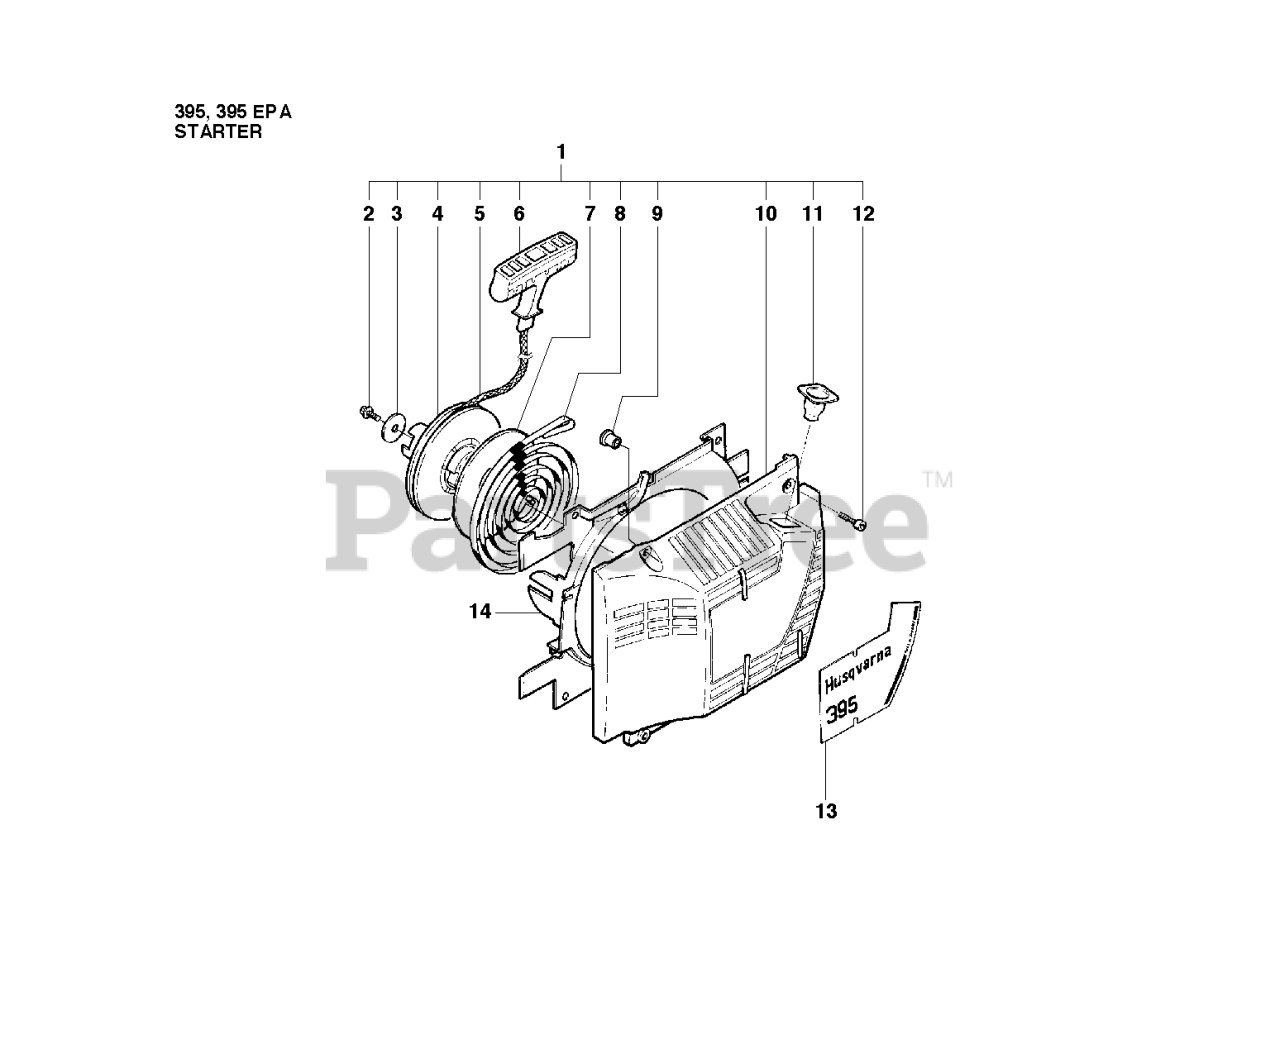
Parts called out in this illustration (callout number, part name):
1	STARTER HOUSING ASSY.
2	SCREW
5	STARTER ROPE
6	STARTER HANDLE
8	RECOIL SPRING
10	STARTER HOUSING
12	SCREW.CCRPANMO.M5X19 10.9 TBO
13	STARTING DECAL
14	AIR CONDUCTOR
